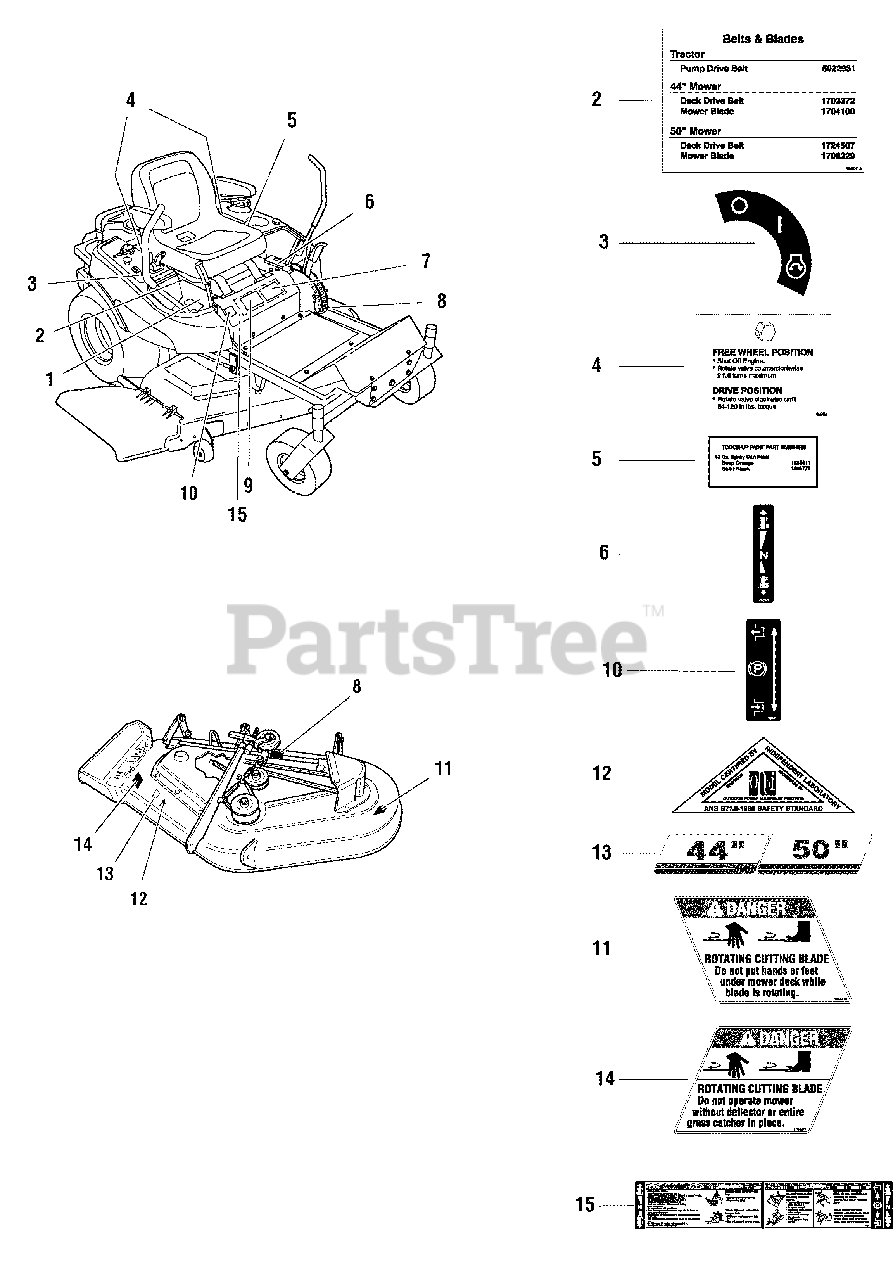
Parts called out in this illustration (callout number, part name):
1	DECAL, Motion Control, RH
2	DECAL, Belt & Blade
2	DECAL, Belt and Blade
3	DECAL, Ignition Switch Symbol, White/Black
4	DECAL, Transmission Release, Free Wheel
4	DECAL, CZT Hydro Release
5	DECAL, Touch Up Paint, Orange/Black
5	DECAL, Touch Up Paint, Red/Black
6	DECAL, Motion Control, LH
7	DECAL, Danger
8	DECAL, I.D. Plate
9	DECAL, Warning
10	DECAL, Parking Brake
11	DECAL, Danger Mower
11	DECAL, Danger Do Not Put Hands/Feet in Mower
12	DECAL, Danger, Mower Discharge
12	DECAL, OPEI Certified
14	DECAL, Danger Do Not Operate Without Deflector
15	DECAL, Long Front of Seat Citation
